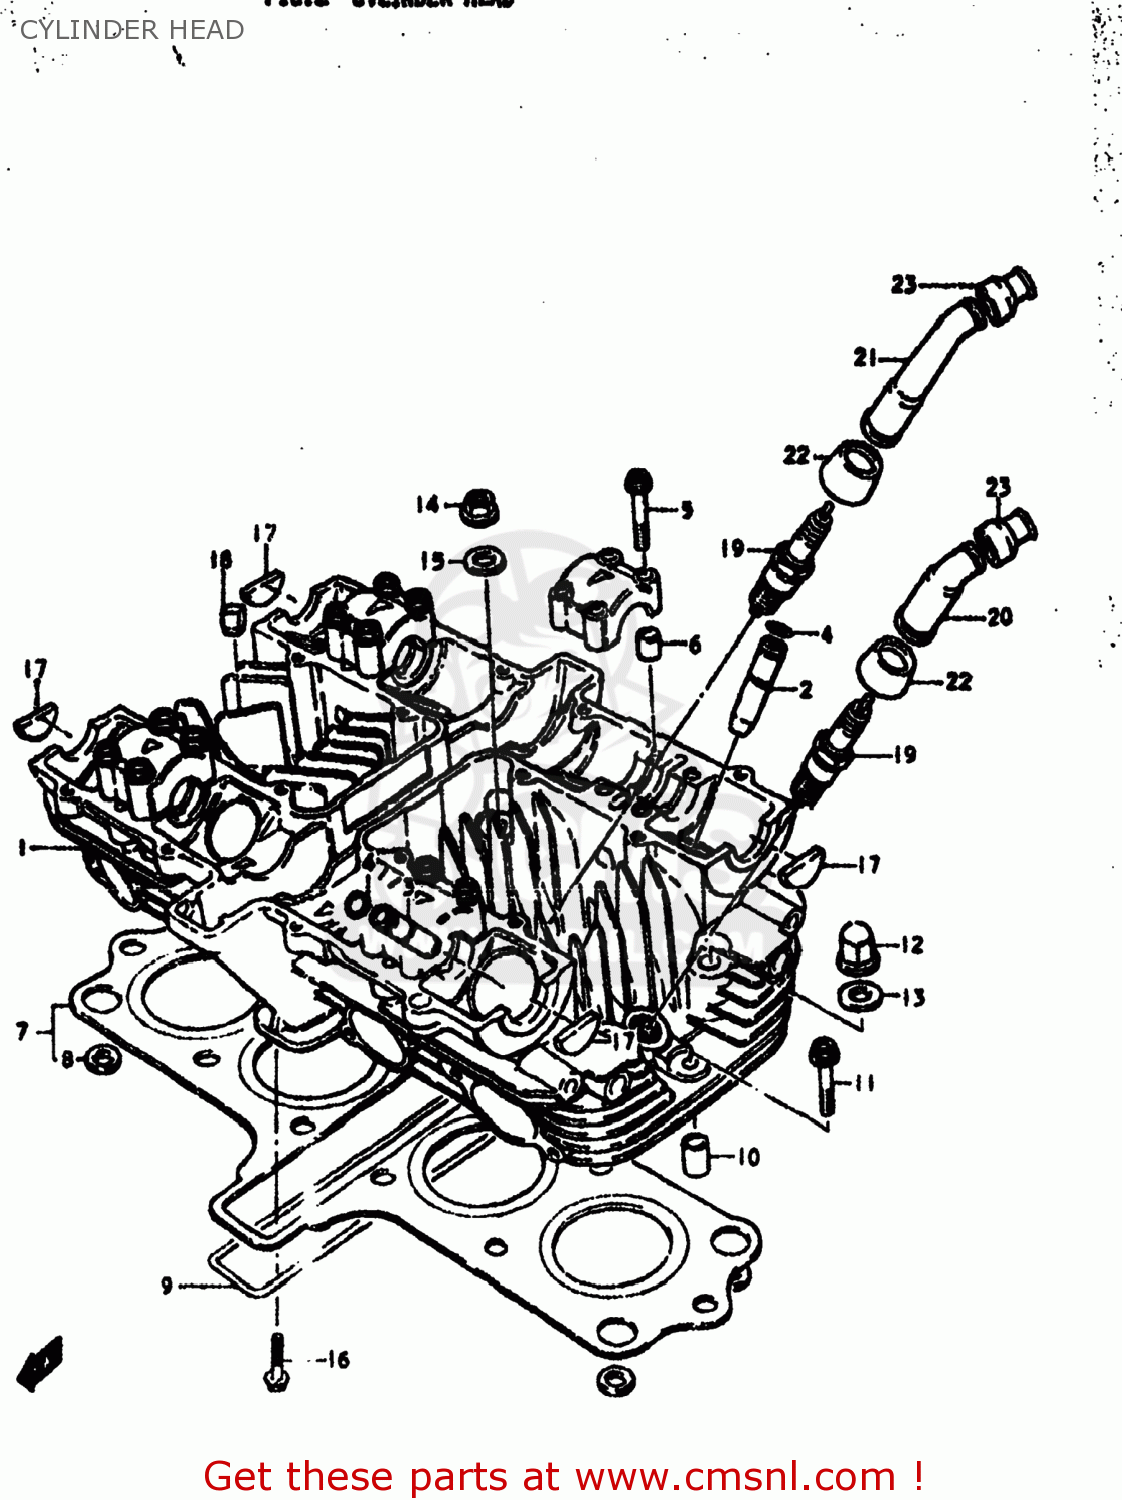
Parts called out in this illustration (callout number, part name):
1	HEAD ASSEMBLY,CYLINDER
2	GUIDE,VALVE
3	GUIDE,VALVE
4	RING,SNAP
5	BOLT(6X39)
6	PIN(6.2X8X11)
7	GASKET,CYLINDER HEAD (MCA)
8	O RING,CYLINDER HEAD GASKET
9	O RING(D:3,ID:26X157)
10	PIN
11	BOLT,UNDER
12	NUT
13	GASKET (NAS)
14	NUT
15	WASHER(8.5X19X2.3)
16	BOLT
17	PLUG
18	PAD
19	PLUG,SPARK
20	CAP,SPARK PLUG
21	CAP ASSY,SPARK PLUG
22	SEAL,SPARK PLUG
23	SEAL,SPARK PLU
